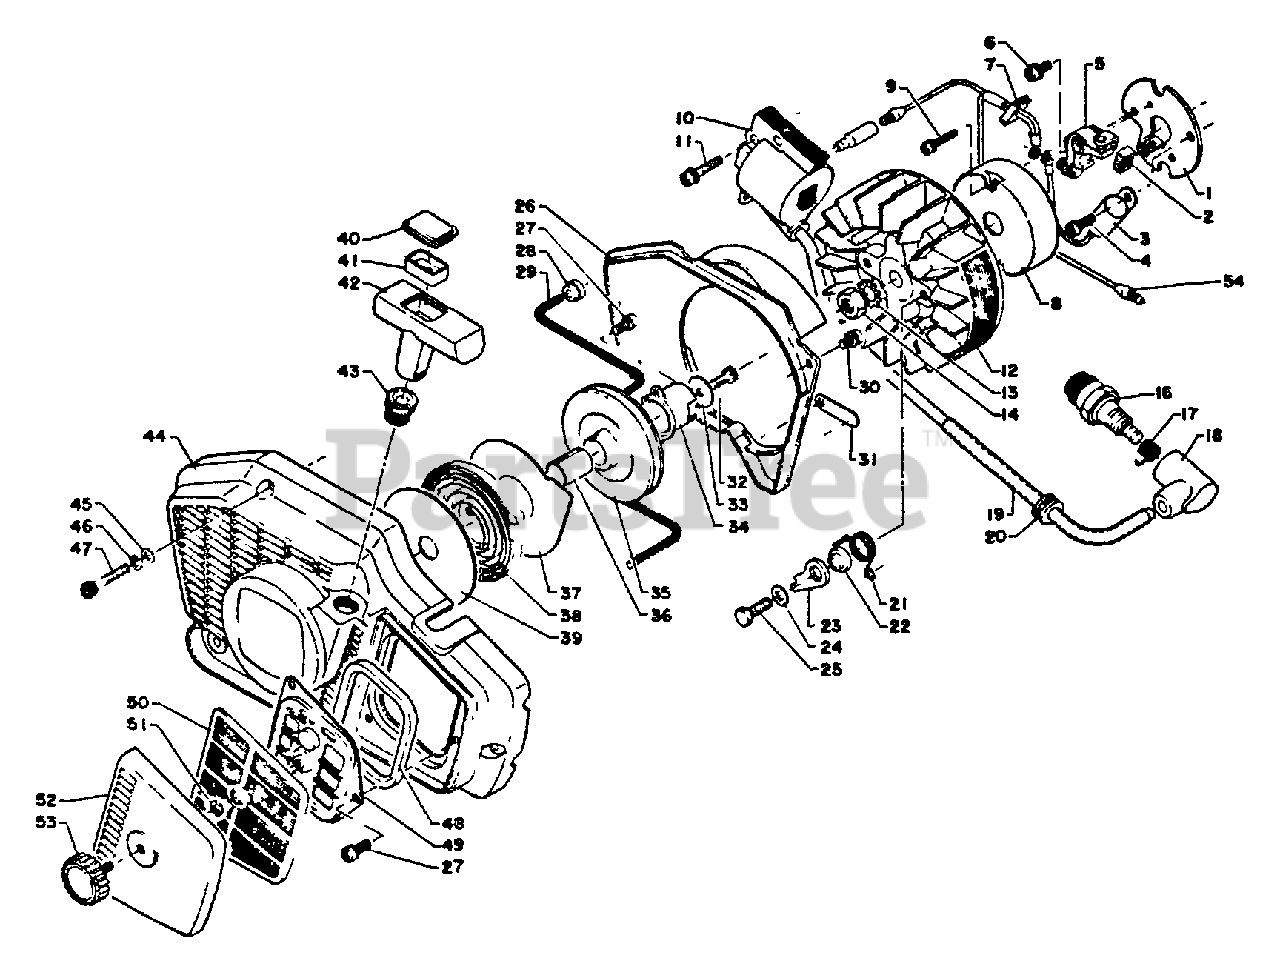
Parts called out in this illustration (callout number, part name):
1	PLATE, STATOR
2	PAD
3	CONDENSER
4	SCREW - 4X10
5	CONTACT POINT SET
6	SCREW - 4X10
8	COVER, BREAKER
9	SCREW - 3X25
10	COIL, IGNITION
11	SCREW - 4X20
12	FLYWHEEL
13	LOCKWASHER - 8
16	SPARK PLUG -- BM-6A
16	SPARK PLUG -- BMR-6A
17	TERMINAL, SPARK PLUG CAP
18	CAP, SPARK PLUG
19	TUBE
21	SPRING, RETURN
23	PAWL, STARTER
24	WASHER - 5
25	BOLT - 5X16
26	SHIELD, FAN
27	SCREW - 4X8
28	RETAINER, ROPE
29	ROPE, STARTER - 3.5X850
30	SCREW - 4X8
31	Guide plate holder
32	SCREW - 4X14
34	CATCHER, PAWL
35	REEL, ROPE
36	BUSHING
37	PLATE, STARTER
38	SPRING, REWIND
39	PLATE, STARTER
41	RING, RETAINING
42	GRIP, STARTER
43	GUIDE, ROPE
44	CASE, STARTER
47	SCREW - 4X25
48	SEAL
49	PLATE
50	FILTER, AIR
51	RING, RETAINING - 3
52	COVER, AIR FILTER
53	THUMBSCREW
54	LEAD
